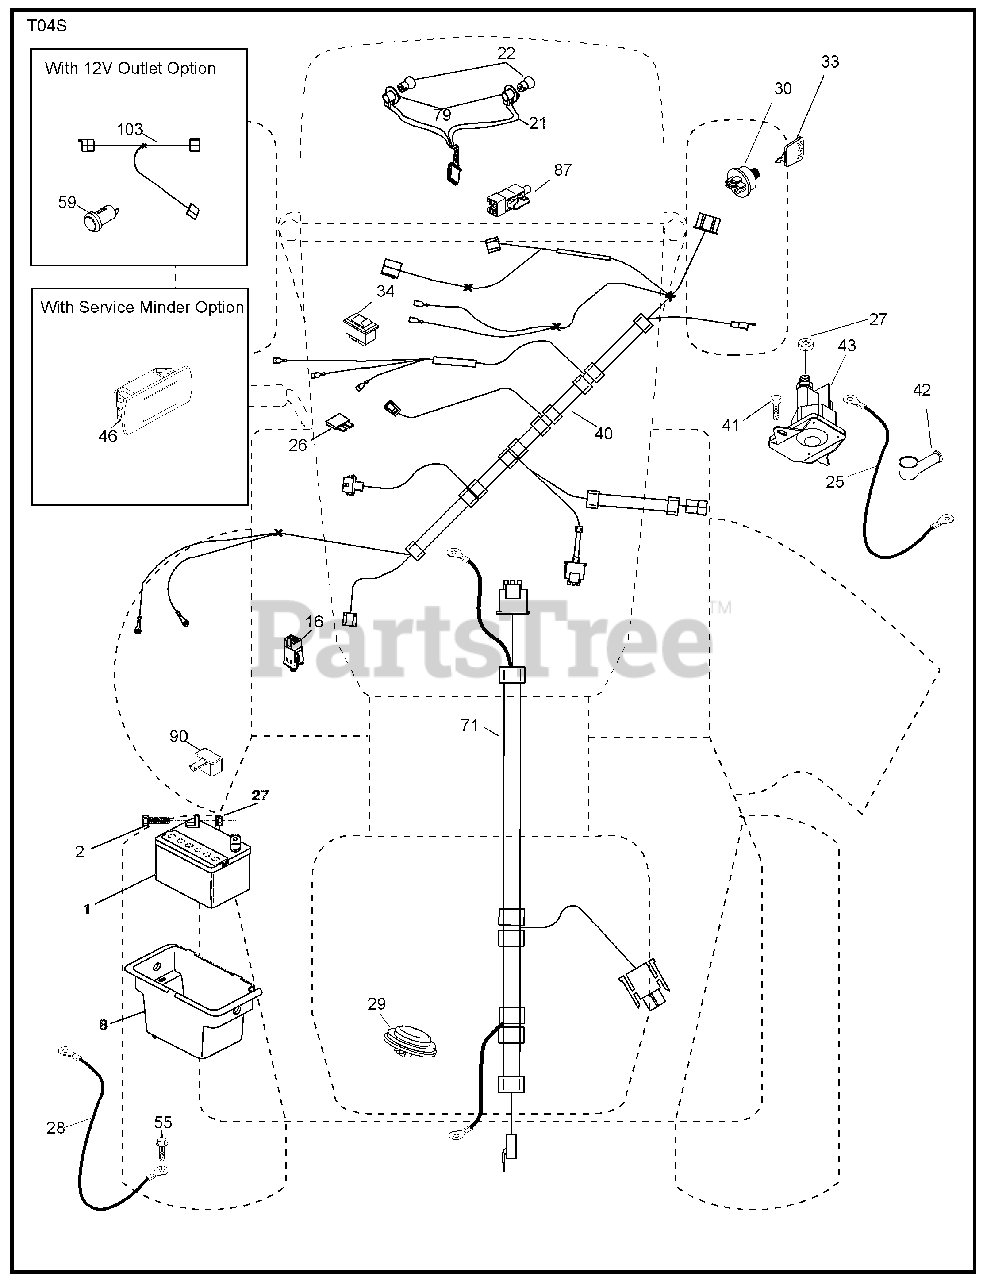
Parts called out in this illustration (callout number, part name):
1	Battery
2	Bolt Hex Head 1/4-20 x 3/4
8	Box Battery
16	Switch Interlock Push-In
21	Harness Socket Light W/4152J
22	Bulb Light
25	Cable Starter
27	Nut Keps Hex 1/4-20 unc
28	Cable, Ground
29	Switch, Seat
30	Switch, Ign
33	Key/Chain
34	Switch Light / Reset
40	Harness Ign.
41	Screw Thd Cut 1/4-20 x 1/2
42	Cover, Terminal
43	Solenoid
46	Gauge Servicereminder Hrmtr
55	Screw Thdrol 5/16-18 x 3/4 TYTT
71	Harness Ign. Dash
79	Socket Asm. Bulb
90	Cover Terminal
